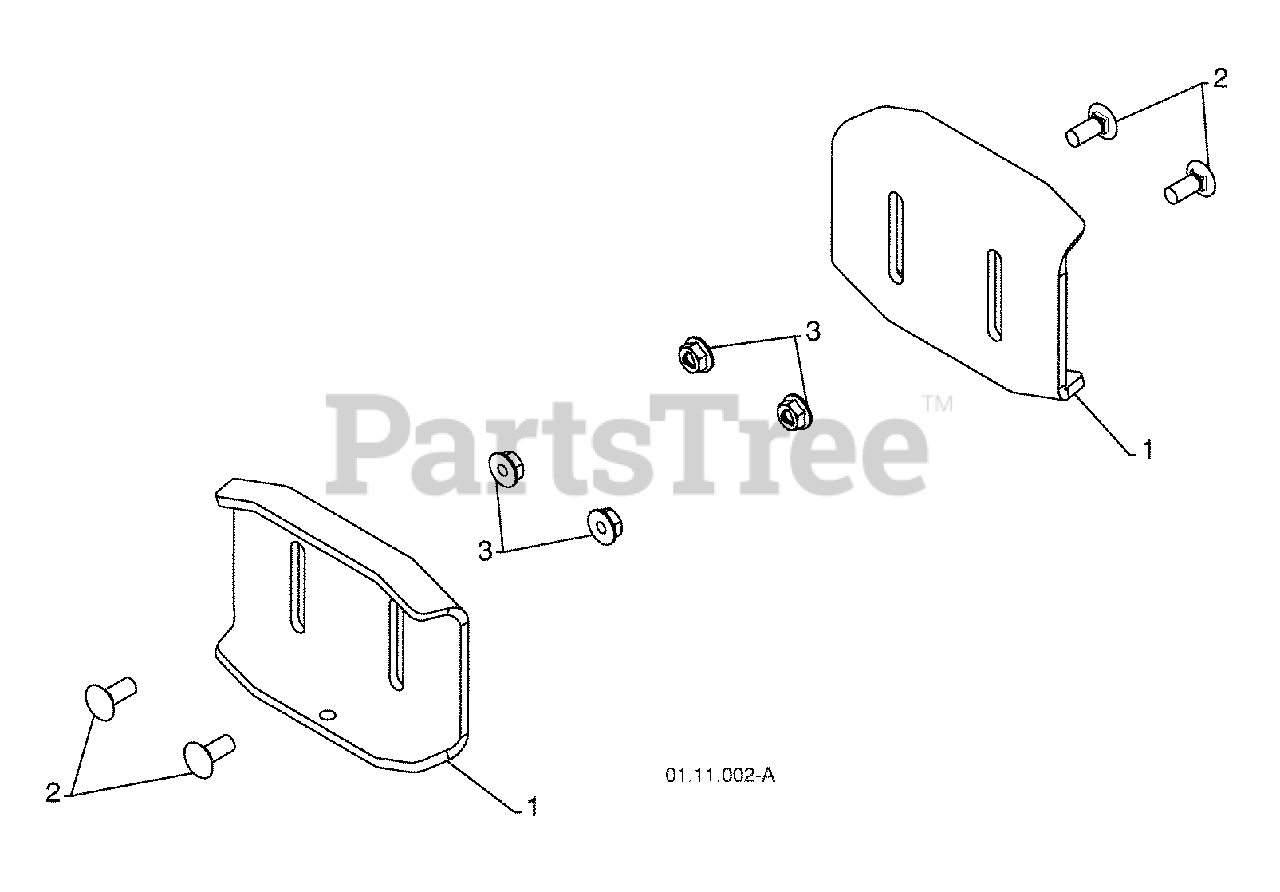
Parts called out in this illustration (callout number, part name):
1	SKID PLATE
2	CARRIAGE BOLT 5/16-18 X .750
3	NUT 5/16-18
